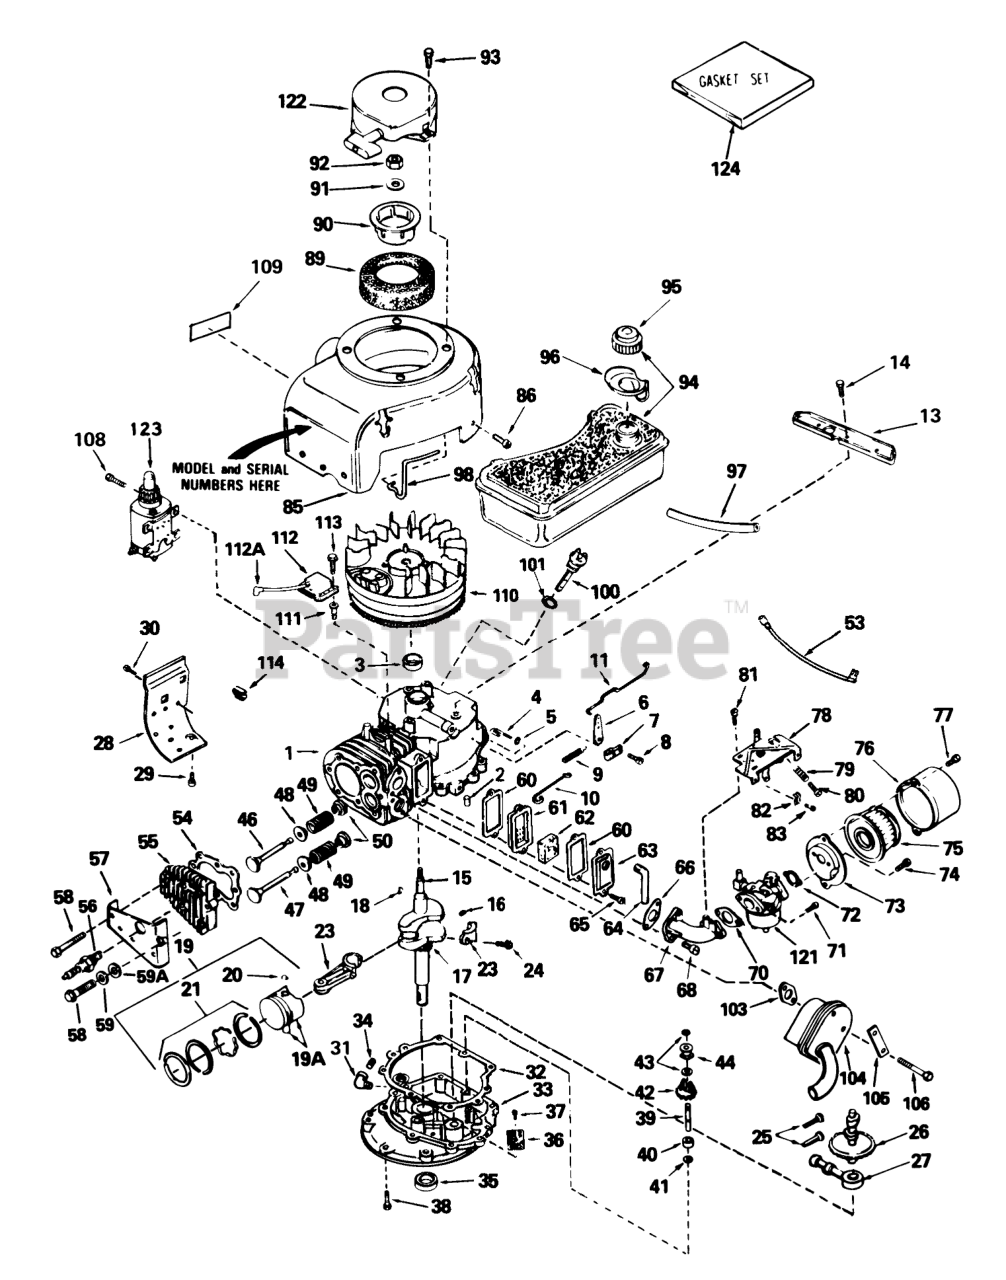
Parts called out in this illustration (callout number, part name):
1	Cylinder Assembly (Incl. #2, 3, 100 & 101)
2	Pin-Dowel
3	Oil Seal
4	Rod-Governor (Incl. #5)
5	Washer-Flat
6	Lever-Governor
7	Clamp-Lever, Governor
8	Screw
9	Spring Governor
10	Link Governor Spring
11	Link Governor
13	Bracket-Blower Housing
14	Screw (1/4-20x19/32)
15	Crankshaft Assembly (Incl. #16 & 17)
16	Pin, Groove
17	Gear-Crankshaft
18	Key-Flywheel
19	Piston-Pin & Ring Assembly (Std.) (Incl. #19A, 20 & 21)
19	Piston-Pin & Ring Assembly (.010 oversize) (Incl. #19A, 20 & 21)
19	Piston-Pin & Ring Assembly (.020 oversize) (Incl. #19A, 20 & 21)
19A	Piston & Pin Assembly (Std.) (Incl. #20)
19A	Piston & Pin Assembly (.010 oversize) (Incl. #20)
19A	Piston & Pin Assembly (.020 oversize) (Incl. #20)
20	Ring-Retaining, Piston Pin
21	"O"Ring
21	Ring Set (.010" OS)
21	Ring Set (.020" OS)
23	Rod Assembly-Connecting (Incl. #24)
24	Bolt-Connecting Rod
25	Lifter-Valve
27	Pump, Oil
28	Extension-Blower Hsng.
30	Screw
31	Street Elbow (90 degrees) (Can be purchased locally)
32	Gasket-Cover, Cylinder
33	Flange Assembly-Mounting (Incl. #34-37, 39 & 41)
34	Plug-Drain, Oil (SQH 1/4-18)
35	Seal-Oil
36	Screen-Oil Filter
38	Screw (1/4-20 x 1-1/4)
39	Shaft, Governor
40	Spacer Assembly-Governor (Incl. #41)
41	Washer-Flat
42	Gear Assembly-Governor (Incl. #41)
43	Ring-Retaining
44	Spool-Governor
46	Valve-Intake (Std.) (Incl. #50)
46	Valve-Intake (1/32" oversize) (Incl. #50)
47	Valve-Exhaust (Std.) (Incl. #50)
47	Valve-Exhaust (1/32" oversize) (Incl. #50)
48	Cap-Spring, Valve
49	Spring-Valve
50	Keeper-Spring, Valve
53	Wire-Ground
54	Gasket-Cylinder Head
55	Head-Cylinder (Incl. 3 of #58)
56	Plug, Spark (J17LM or equiv.)
56	Plug, Spark (Champion RCJ-8)
57	Cover-Head, Cylinder
58	Screw (5/16-18 X 2-1/2)
59	Washer-Belleville
59A	Washer-Flat
60	Gasket-Breather
61	Body-Breather
62	Element-Breather
63	Cover-Valve
64	Tube-Breather
66	Gasket-Intake
67	Pipe-Intake
68	Screw (T-30, 5/16-18x1-3/32)
70	Gasket
71	Screw-Hex Hd.
72	Gasket
73	Bracket
74	Screw (10-32 x 1/2)
75	Element
76	Body-Air Cleaner
78	Control Assembly-Speed (Incl. #79 & 80)
79	Spring-Compression
80	Screw
81	Screw (10-24 x 9/16)
82	Conduit
83	Screw (10-32 x 3/8)
85	Housing-Blower
89	Screen-Starter
90	Cup-Starter
91	Washer-Belleville
94	Tank Assembly-Fuel (Incl. #95)
95	Cap-Fuel
96	Deflector-Fuel
97	Line-Fuel (8.62)
98	Clamp, Tank Holdown
100	Dipstick-Oil (Incl #101)
101	Gasket
103	Gasket Exhaust
104	Muffler
105	Plate-Locking
106	Screw Hex Hd.
108	Screw
109	Decal-Instruction
110	Flywheel
111	Stud
112	Solid State
112A	Cover-Spark Plug
113	Screw
114	Clip, Spring
121	Carburetor (Incl. #70)
122	tarter-Rewind
123	Tine Shaft
124	Gasket Set
